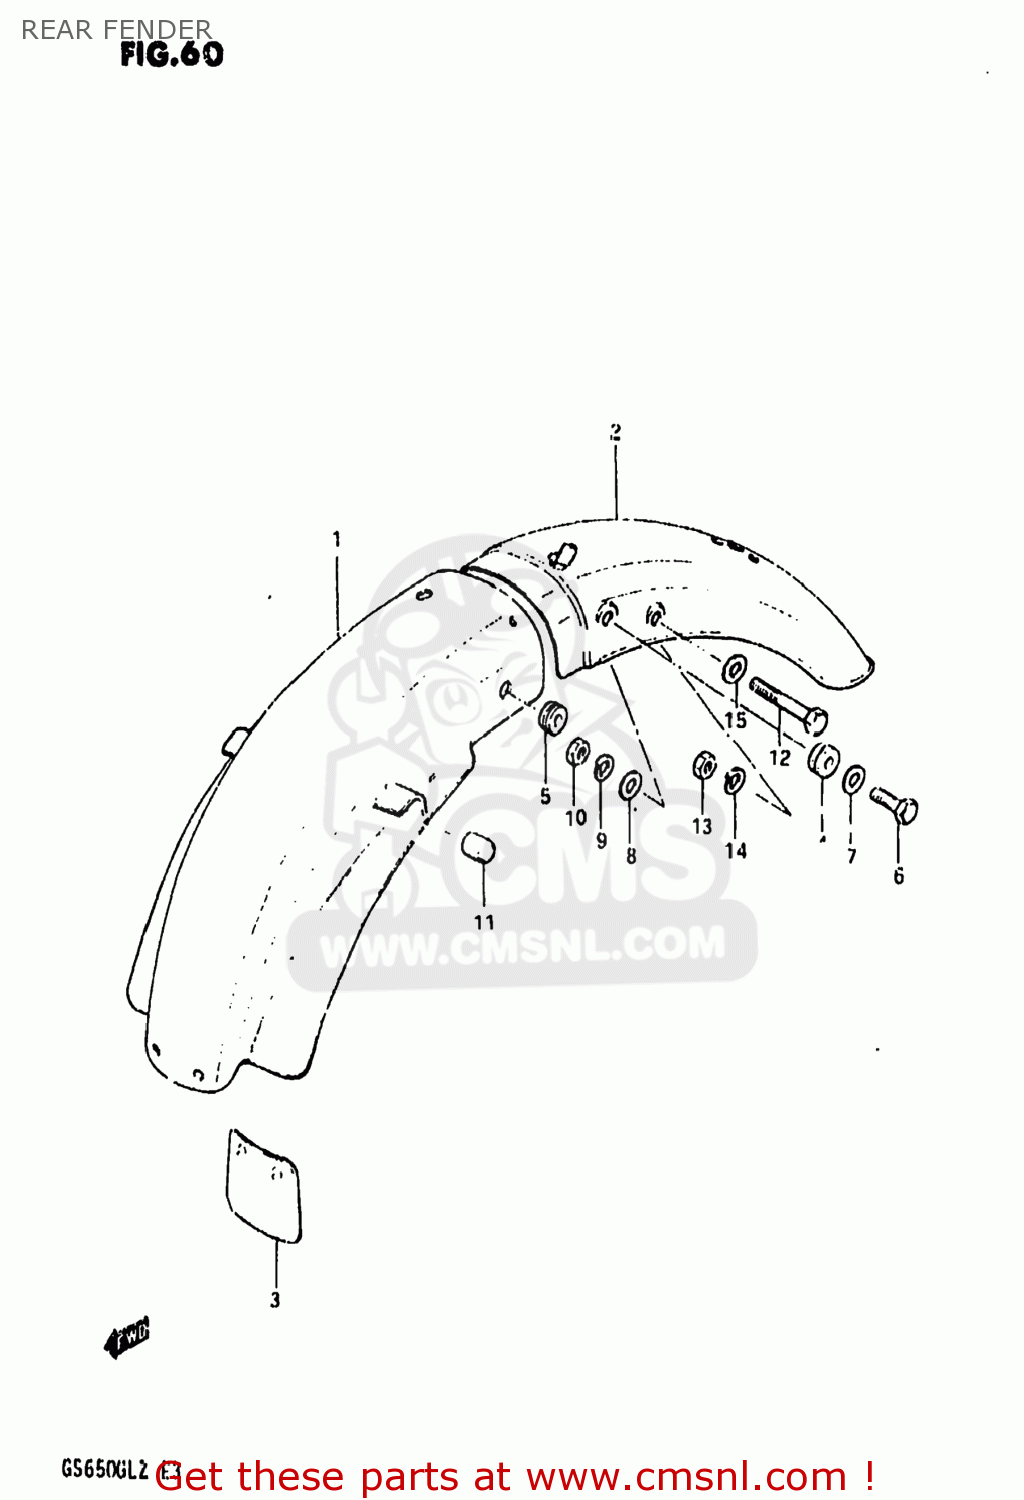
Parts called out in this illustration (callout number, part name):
1	FENDER,REAR
2	FENDER,REAR
3	GUIDE,RR FENDER MUD
4	CUSHION
5	CUSHION
6	BOLT
7	WASHER
8	WASHER
9	LOCK WASHER
10	NUT
11	CUSHION
12	BOLT
13	NUT 8MM
14	LOCK WASHER
15	WASHER
